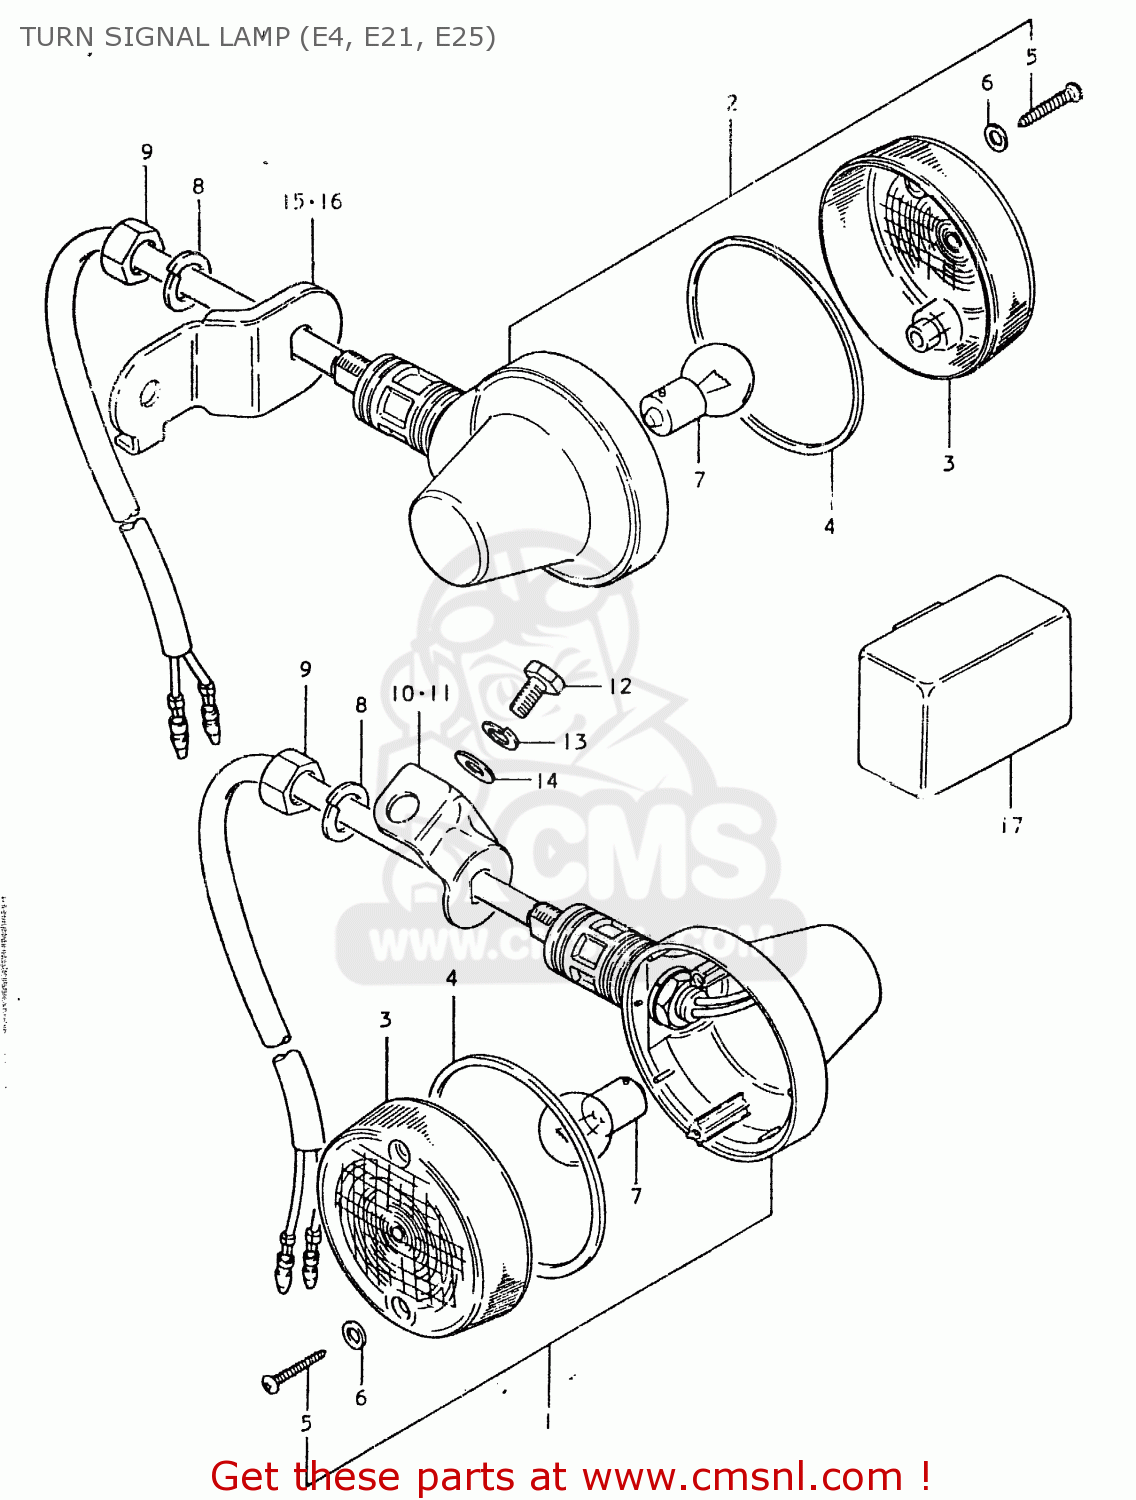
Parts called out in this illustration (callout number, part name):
1	LAMP ASSY,RR TURNSIGNAL
2	LAMP, REAR TURN SIGNAL
3	LENS
4	GASKET (NAS)
5	SCREW TAPP.
6	GASKET (NAS)
7	BULB(6V/10W,STANLEY,A4117)
8	WASHER,LOCK 12
9	NUT
10	BRACKET,TURNSIGNAL LAMP,R
11	BRACKET,TURNSIGNAL LAMP,L
12	BOLT
13	LOCK WASHER
14	WASHER
15	BRACKET,REAR TURN SIGNAL
16	BRACKET,REAR TURN SIGNAL
17	RELAY, TURN SIGNAL
